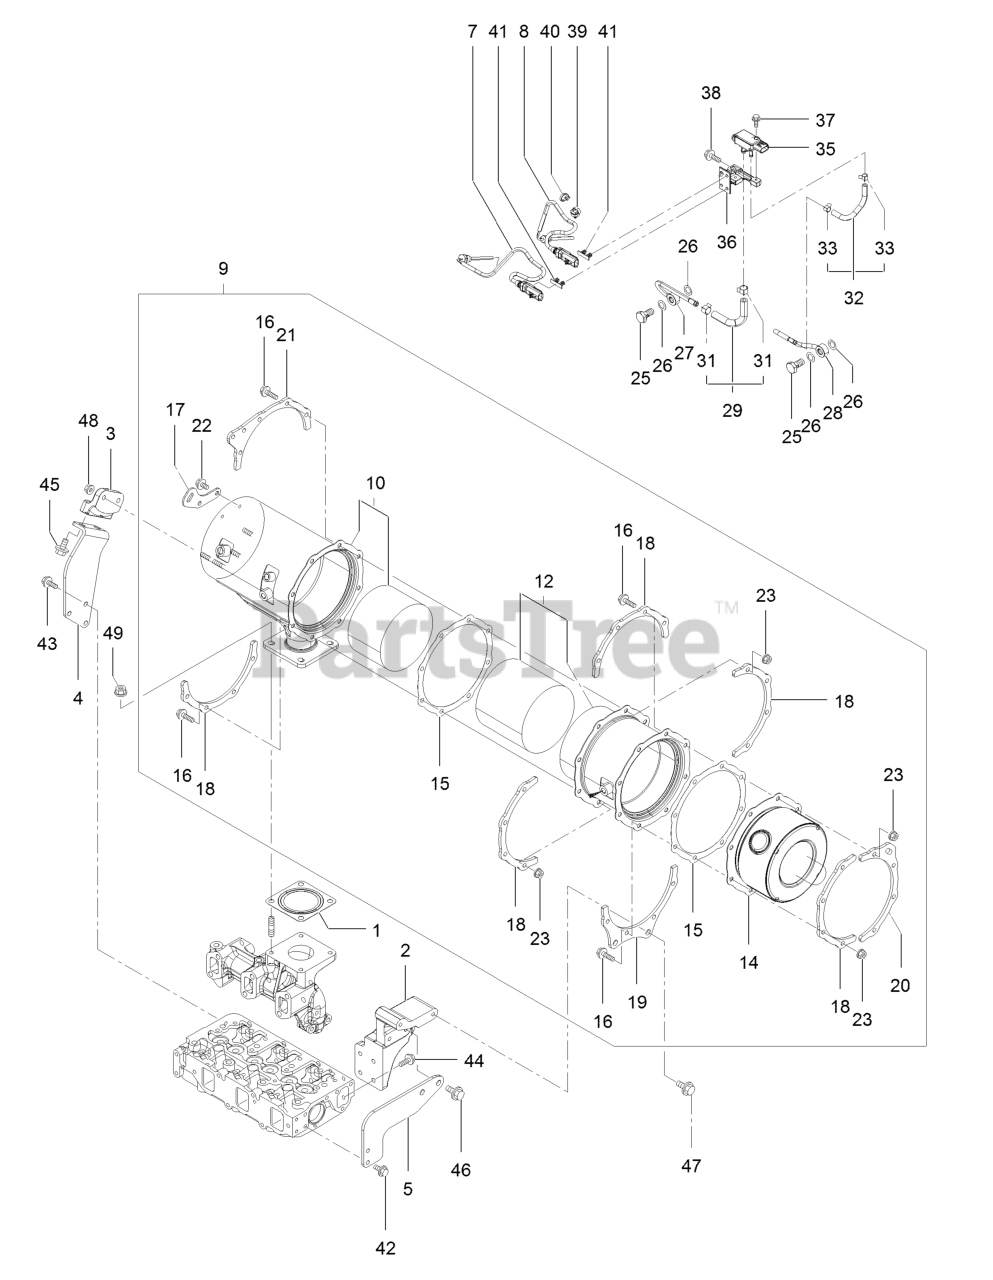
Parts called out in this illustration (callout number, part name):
1	Gasket-Silencer
2	Stay-D P F
3	Stay-D P F
4	Stay-D P F
5	Stay-D P F
7	Sensor-Temp, Exhaust
8	Sensor-Temp, Exhaust
9	D P F ASM
10	Case-D O C
12	Case-Filter, Soot
14	Silencer-D P F
15	Gasket-D P F
17	Lifter-D P F
18	Stiffener-D P F, A
19	Stiffener-D P F, B
20	Stiffener-D P F, C
21	Stiffener-D P F, C
25	Bolt-Joint, Pipe
26	Gasket-Sensor
27	Sensor Pipe ASM
28	Sensor Pipe ASM
29	Exhaust Hose ASM
31	Clip-Hose
32	Exhaust Hose ASM
33	Clip-Hose
35	Sensor-Pressure
36	Bracket-Sensor
39	Band-Clip
41	Clip-Connnector
42	Bolt
43	Bolt
